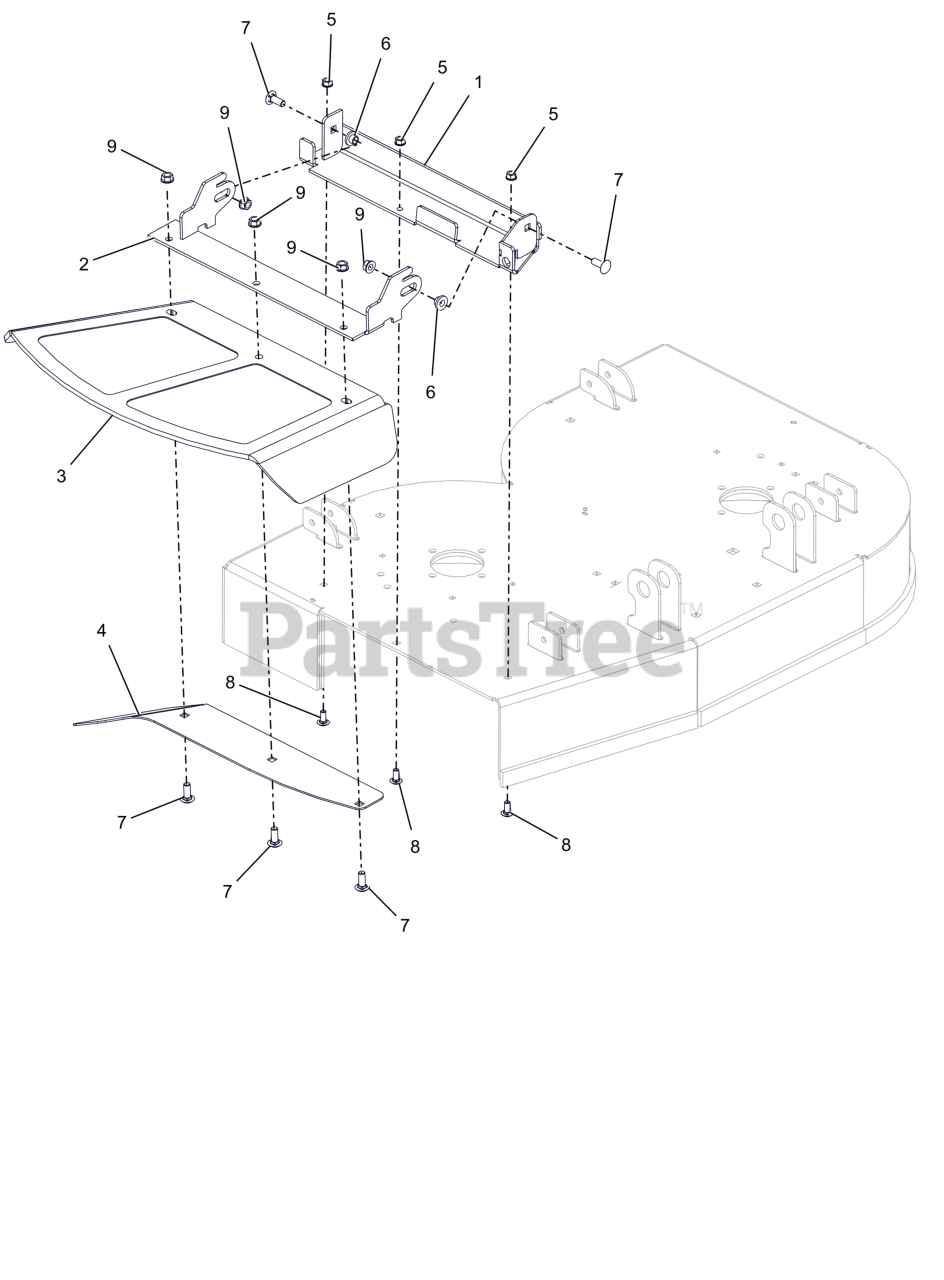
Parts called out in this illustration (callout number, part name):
1	WLDMT, DISCHARGE CHUTE (RED)
2	WLDMT, 36" CHUTE MTG BRKT (RED)
3	CHUTE,48-60" FRMD RUBBER DISCH
4	PLATE, 32-36" DISCH CHUTE CLAMP (BLACK)
5	NUT,LK-CTR-FLG .31-18 GF ZCC
6	BSHG-FLG .385X.500X.875X.406
7	BLT,RHSSN .38-16X1.00 G5 ZCC
8	BLT, RHSSN.31-18X.750 G5 ZCC
9	NUT-LK-CTR-FLG .375-16 GF ZCC
